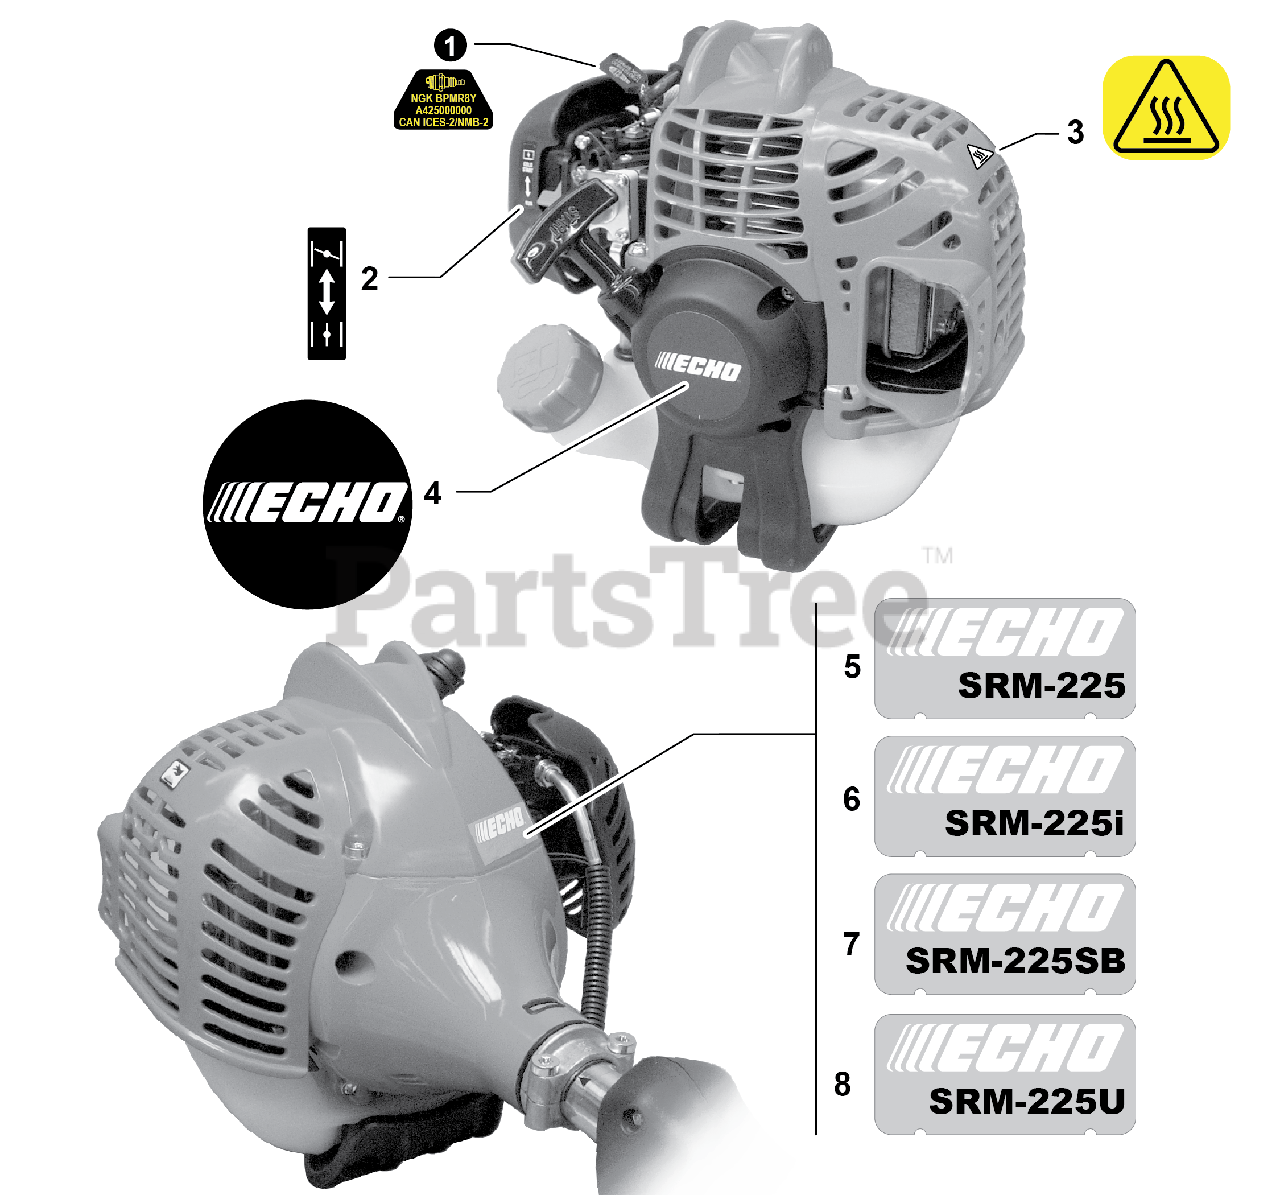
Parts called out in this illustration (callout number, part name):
1	LABEL - SPARK PLUG - BPMR8Y
2	LABEL - CHOKE
3	LABEL - CAUTION - HOT
4	LABEL - STARTER - ECHO
5	LABEL - MODEL SRM-225
6	LABEL - MODEL SRM-225I
7	LABEL - MODEL SRM-225SB
8	LABEL - MODEL SRM-225U
